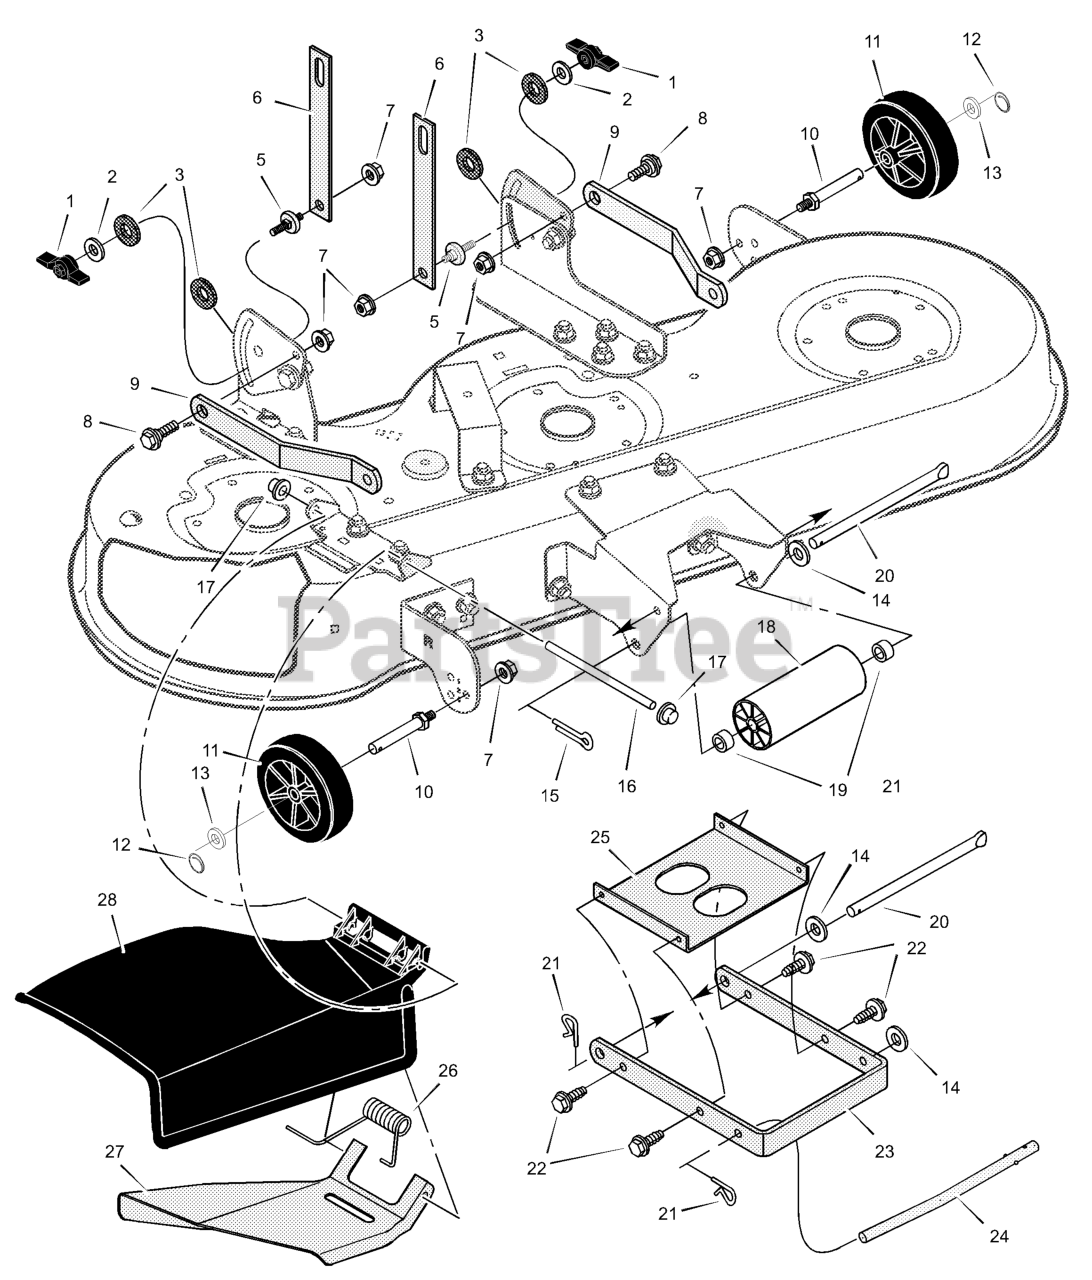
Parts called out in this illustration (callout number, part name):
1	Knob
3	Pad, Friction
5	Pin, Hanger
6	Link, Lift
7	Nut, Flange
8	Bolt, Shoulder
9	Bracket, Rear Suspension
10	BOLT, Gauge Wheel
12	Pin, Hair
15	Pin, Cotter
16	Rod, Deflector
17	Push-On Cap
20	Rod, Deck Suspension
21	Pin, Hair
23	Bracket, Front Suspension
24	Rod, Hanger
25	Stiffener
27	Deflector, Inside
28	Deflector, Chute
